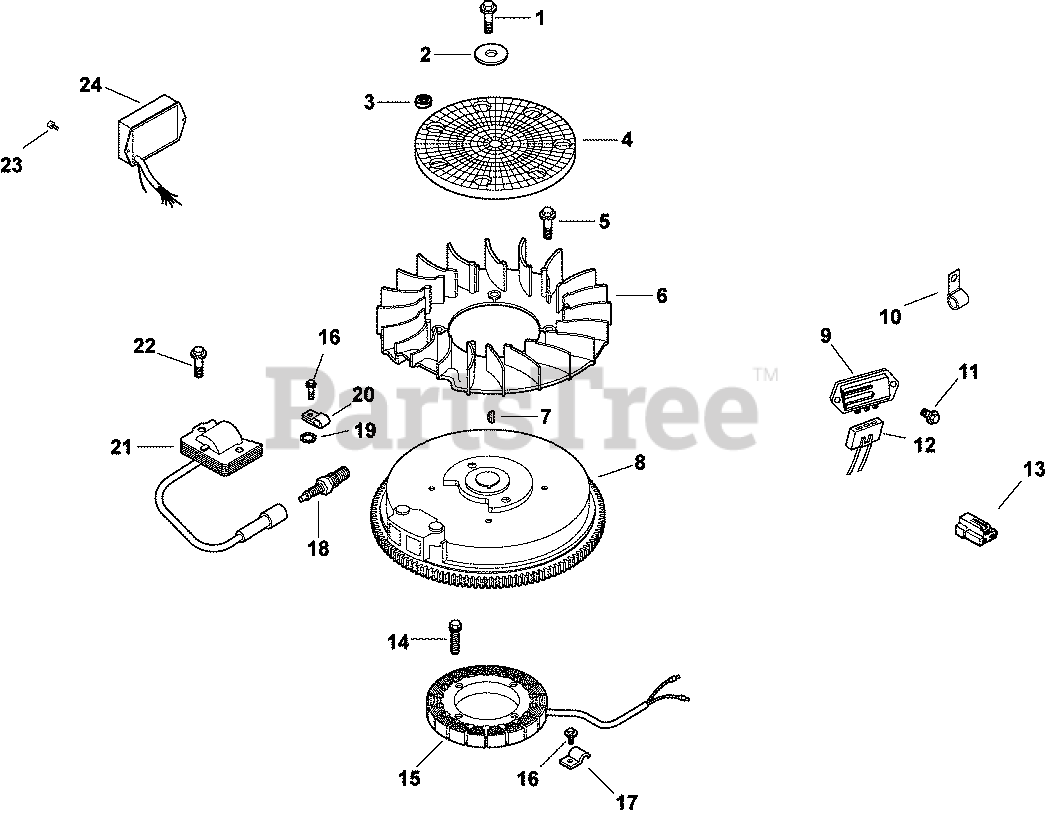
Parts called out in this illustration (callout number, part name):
1	SCREW, FLG M10X1.5X45 - (#25086361S)
2	WASHER, FLAT 13/32"
4	SCREEN, GRASS
5	BOLT, SHOULDER
7	KEY, 3/16" X 5/8"
8	FLYWHEEL - DISCONTINUED
9	REG/RECT-15 AMP (KM)-USE 41 403 10-S
10	CLIP, CABLE
11	SCREW, PHL HD #11-16X7/8"
12	CONNECTOR, BODY (KM)-USE 25 155 41-S
13	CONNECTOR
14	SCREW, M5X0.8X25 - (#25086402S)
15	KIT, 15 / 20 AMP STATOR
16	SCREW, FLG THD FRM M5X.8X10
18	PLUG, SPARK (STD)
19	WASHER, INT TOOTH LOCK 1/4"
20	CLIP, CABLE
21	MODULE, IGNITION
22	SCREW, SCKT THRD FRMM5X0.8X20 - DISCONTINUED
23	SCREW, PHL THD FRM M4.2X13
24	MODULE, DIGITAL SPD ADV-USE 12 707 01-S
